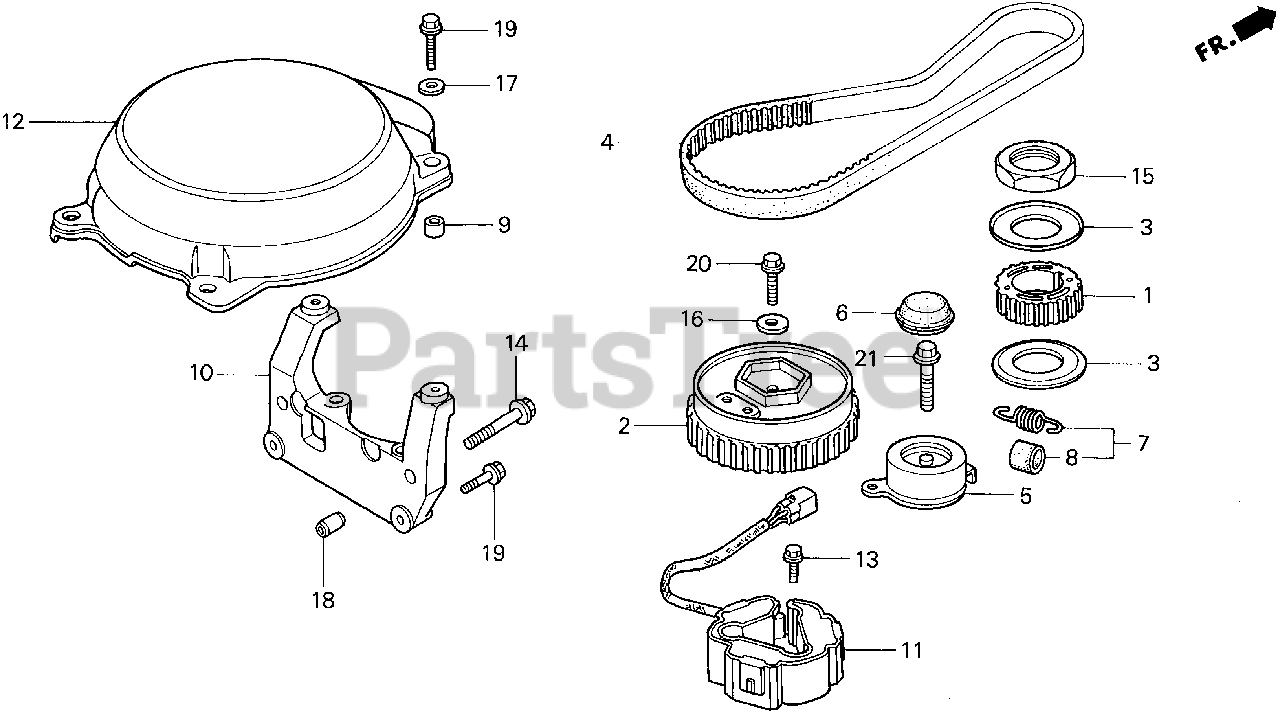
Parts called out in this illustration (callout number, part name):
1	PULLEY, TIMING
2	PULLEY, CAM
3	PLATE, TIMING BELT GUIDE
4	BELT, TIMING
5	TENSIONER, TIMING BELT
6	CAP, TIMING BELT TENSIONER
7	SPRING, TIMING BELT ADJUSTING
8	BOOT, SPRING
9	COLLAR, DISTANCE (6.5X11X7.5)
10	BRACKET, RECOIL
11	COIL ASSY., PULSER
12	COVER, FLYWHEEL
13	BOLT, FLANGE (6X12)
14	BOLT, FLANGE (8X45)
15	NUT, LOCK (34MM)
16	WASHER, PLAIN (8MM)
17	WASHER (6.5X18)
18	PIN A, DOWEL (10X16)
19	BOLT, FLANGE (6X22)
20	BOLT, FLANGE (8X25)
21	BOLT, FLANGE (10X38)
